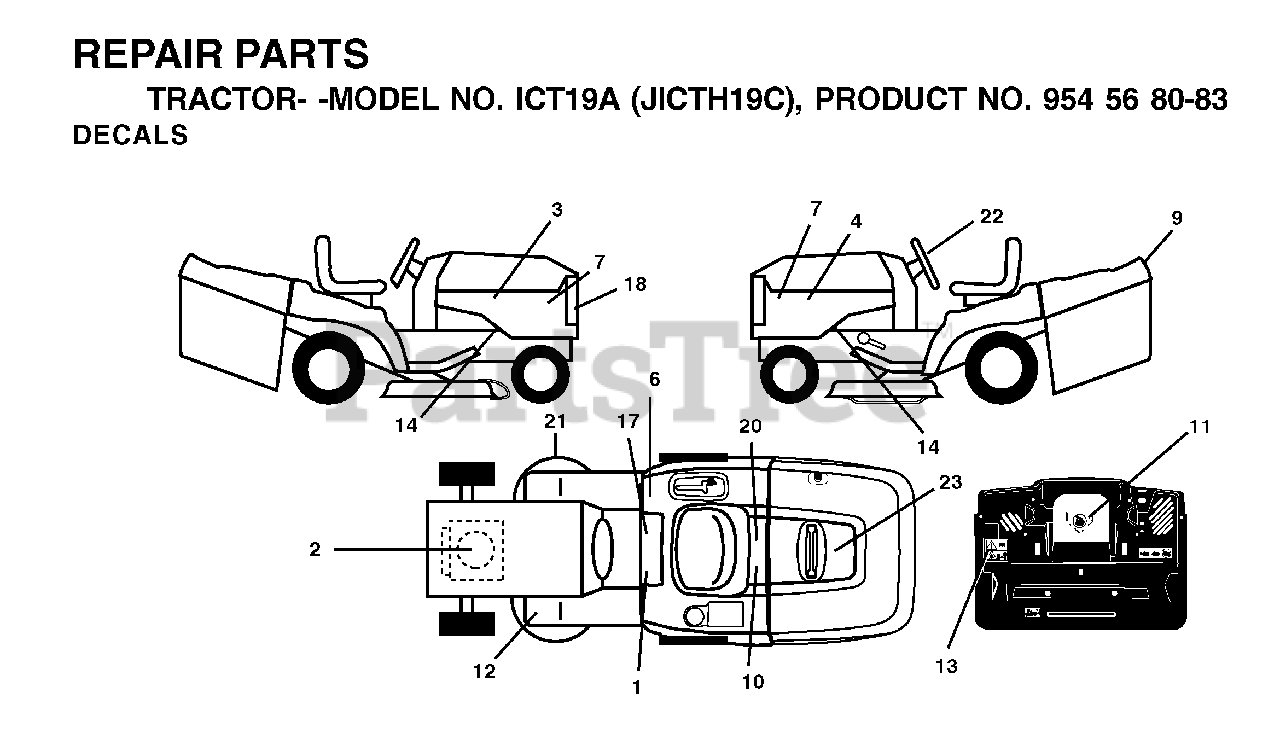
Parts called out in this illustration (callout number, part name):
1	DECAL READ OWNER'S MAN SYMS
10	DECAL BTRY SYMBOLS
11	DECAL.INTERNATIONL.CUTFINGER
17	DECAL PARK BRAKE
20	DECAL.BYPASS.FENDER.CRD.LT.YT
